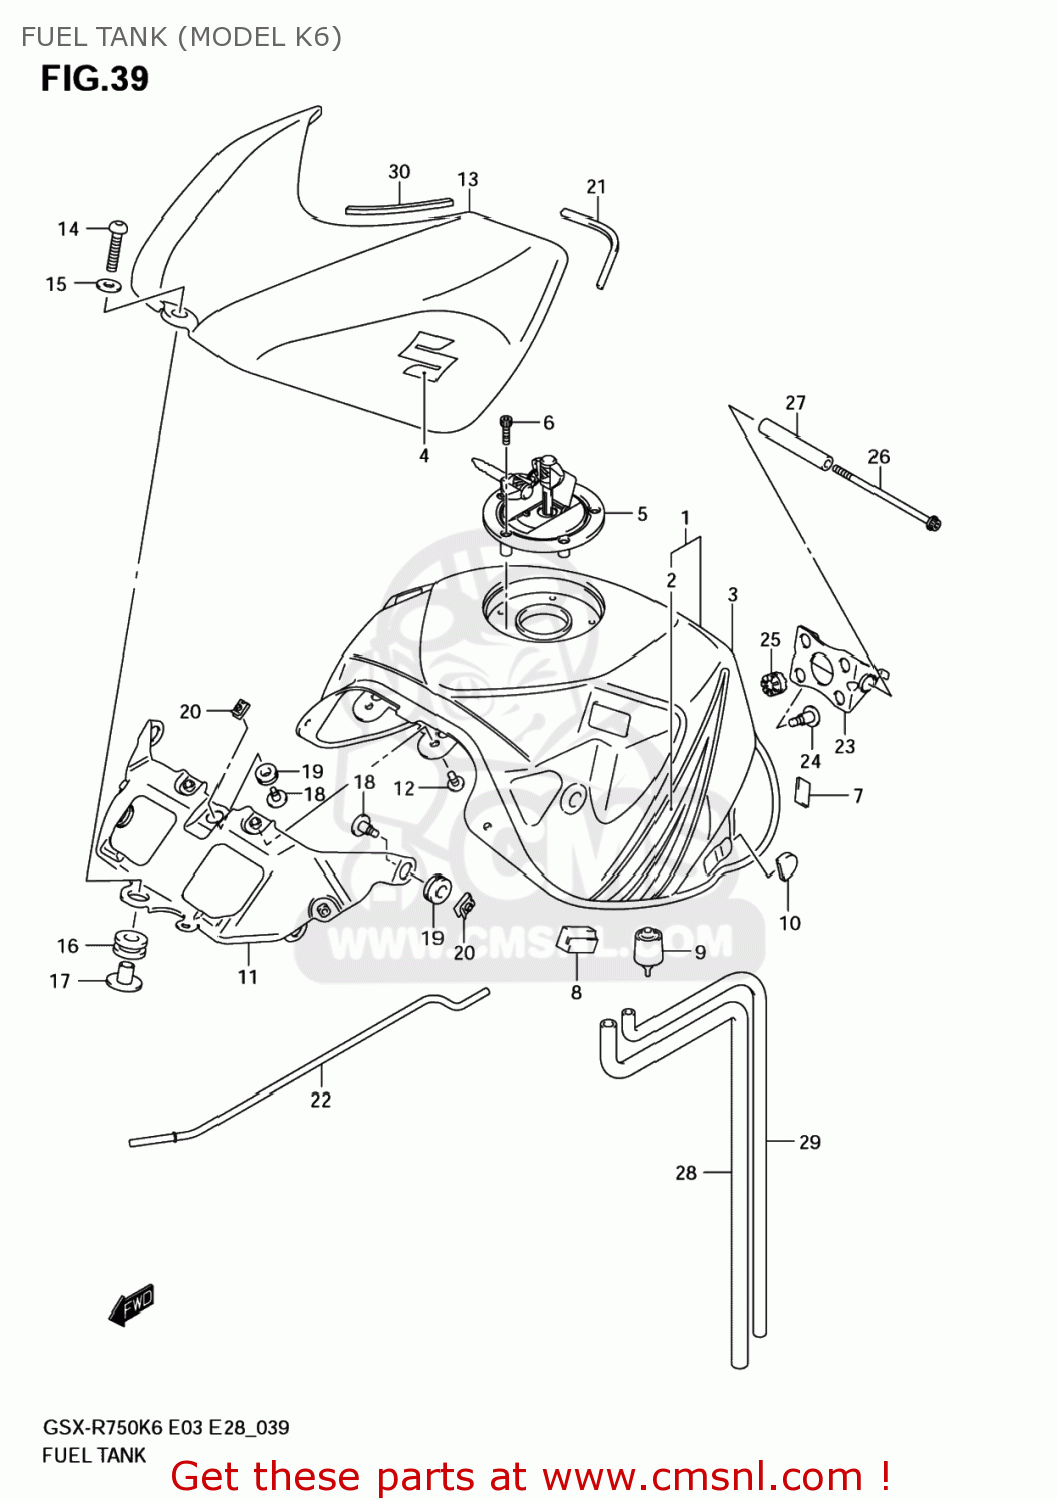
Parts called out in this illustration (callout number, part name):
1	TANK ASSY,FUEL(BLACK)
2	TAPE SET,FUEL TANK
3	TANK ASSY,FUEL(BLACK)
4	EMBLEM,S
5	CAP SET,FUEL TANK
6	BOLT(5X20)
7	FASTENER
8	CUSHION,FUEL TANK SIDE
9	CUSHION,FUEL TANK RR
10	CUSHION
11	BRACKET,FUEL TANK FR
12	SCREW(6X10)
13	COVER,FUEL TANK FR
14	BOLT(8X37)
15	WASHER(8.5X20X1.6)
16	CUSHION
17	SPACER (8.6X12
18	SCREW(5X16.4)
19	CUSHION
20	NUT
21	CUSHION,FUEL TANK COVER
22	STAY,FUEL TANK
23	BRACKET,FUEL TANK NO.1
24	SCREW,FUEL TAN
25	CUSHION
26	BOLT GSX-R1000
27	SPACER,FUEL TANK RR
28	HOSE,TANK WATER DRAIN
29	HOSE,TANK BREATHER
30	CUSHION,TANK COVER
